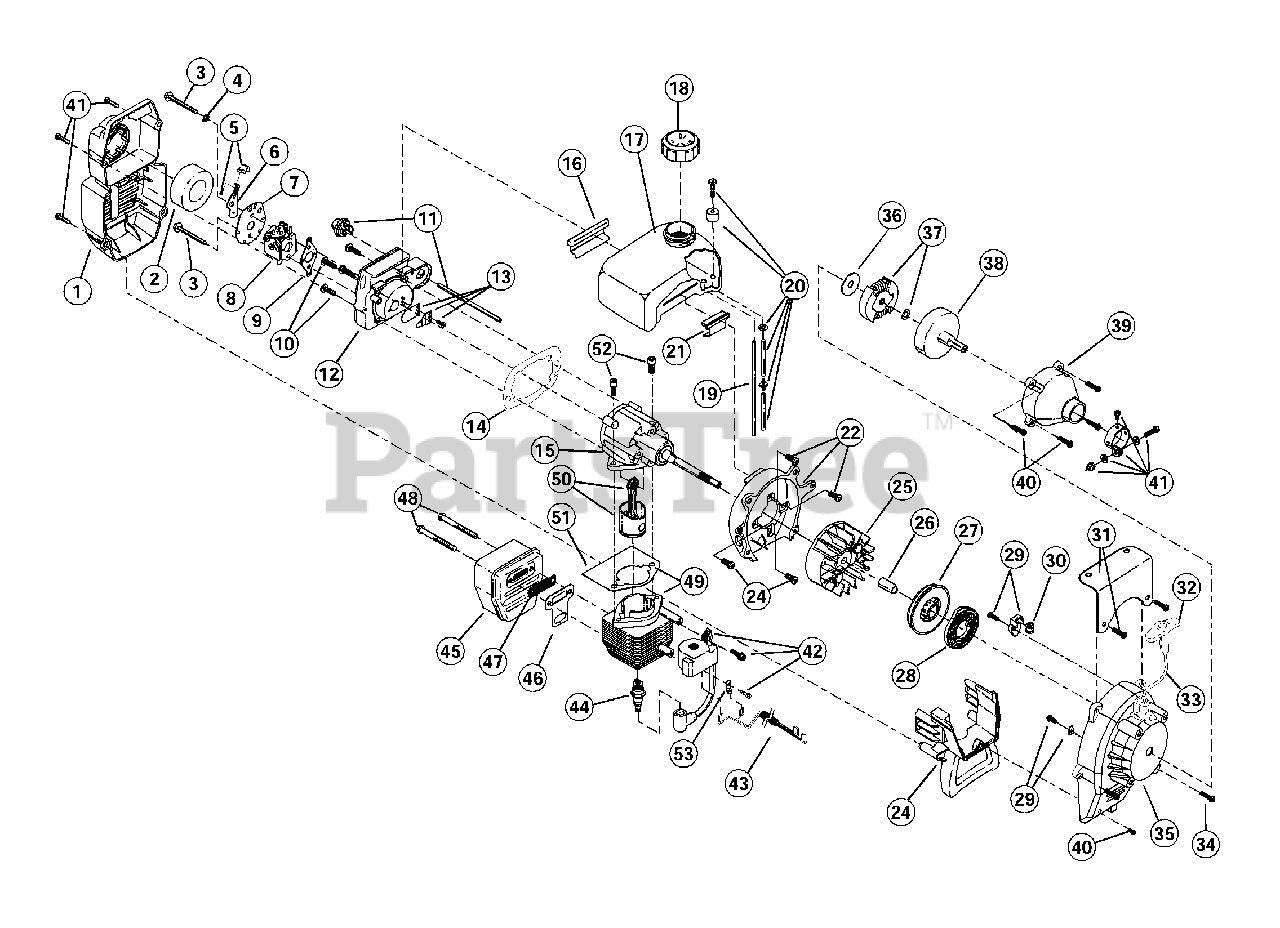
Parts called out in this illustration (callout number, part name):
1	Air Cleaner/Muffler Cover Assembly (includes 2 & 40)
2	Air Cleaner Filter
3	Carburetor Mounting Screw Assembly
4	Wavey Washer
5	Choke Knob & Screw
6	Choke Lever Assembly (includes 5)
7	Choke Lever & Plate (includes 6)
8	Carburetor Assembly (includes 9 & 20)
9	Carburetor Gasket
10	Carb Mount Screw
11	Primer and Hose Assembly
12	Carb Mount Assembly (includes 10 & 13)
13	Reed Assembly
14	Carburetor Mount Gasket
15	Crank Case Service Assembly (includes 10 & 23)
16	Rear Mounting Pad
17	Fuel Tank Assembly (includes 18-20)
18	Fuel Cap Assembly
19	Fuel Return Line
20	Fuel Line Assembly
21	Front Mounting Pad
22	Shroud Assembly
23	Shroud Screw
24	Shroud Extension and Stand (includes 40)
25	Flywheel Assembly
27	Recoil Pulley Assembly
28	Recoil Spring
29	Pulley Retainer Assembly
30	Rope Guide
31	Fuel Tank Guard Assembly
32	Pull Handle
34	Housing Screw
35	Starter Housing Assembly (includes items 27-30, 32-34 & 40)
36	Clutch Washer
37	Clutch Rotor Assembly
38	Clutch Drum Assembly
39	Clutch Cover Assembly (includes 40)
40	Clutch Cover Screw
41	Upper Clamp Assembly
42	Module Assembly (includes 52)
43	Wire Lead
44	Spark Plug
45	Muffler Assembly (includes item 46-48)
46	Exhaust Gasket
47	Spark Arrestor
48	Muffler Mounting Bolt Assembly
49	Cylinder Assembly (includes items 51 & 52)
50	Piston & Rod Assembly
51	Cylinder Gasket
52	Cylinder Bolt
53	Ground Tab
